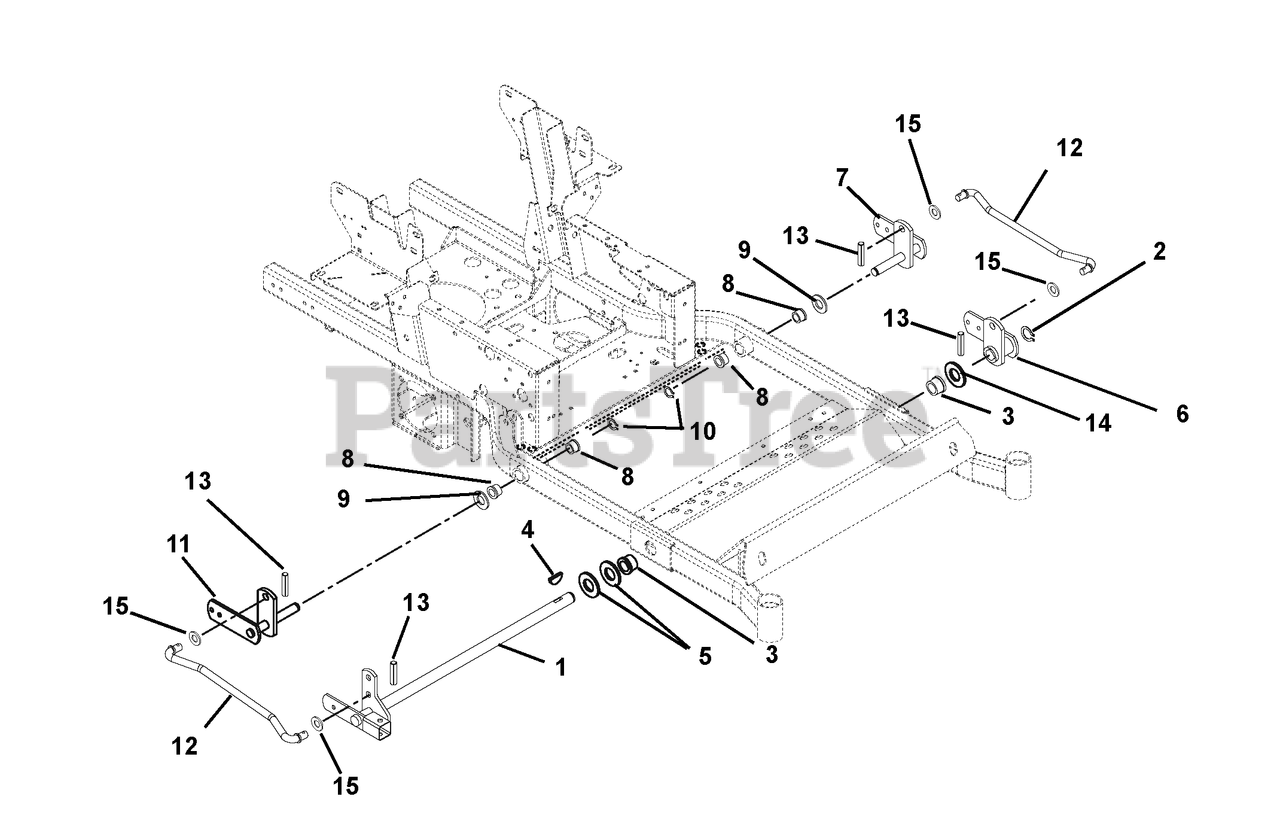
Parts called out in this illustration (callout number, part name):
1	WMT, FRONT MOWER LIFT (HYD)
2	RG-RTNG-EXT 1.00X.078
3	BSHG,1.00ID X 1.125OD X 1.50LG
4	KEY-WDRF .25X1.00 HRD #15
5	WSHR-FL-STL- 1.062X2.0X.134 YZ
6	WMT, LH FRONT MOWER LIFT
7	WMT, LH REAR LIFT ARM
8	BSHG-FLG .762X1.0X.580X1.48 NY
9	WSHR-HDND-THRST .758X1.23X.031
10	RG-RTNG-EXT .689X.078
11	WMT, RH REAR LIFT ARM
12	ROD, LIFT ASSIST 16.35"
13	PIN-ROLL .250X1.25 STNLESS STL
14	WSHR-HDND-THRUST 1.00X1.55X.03
15	WSHR-FL-STL .630X1.250X.062 YZ
16	BSHG-SLV .377X.624X.235
